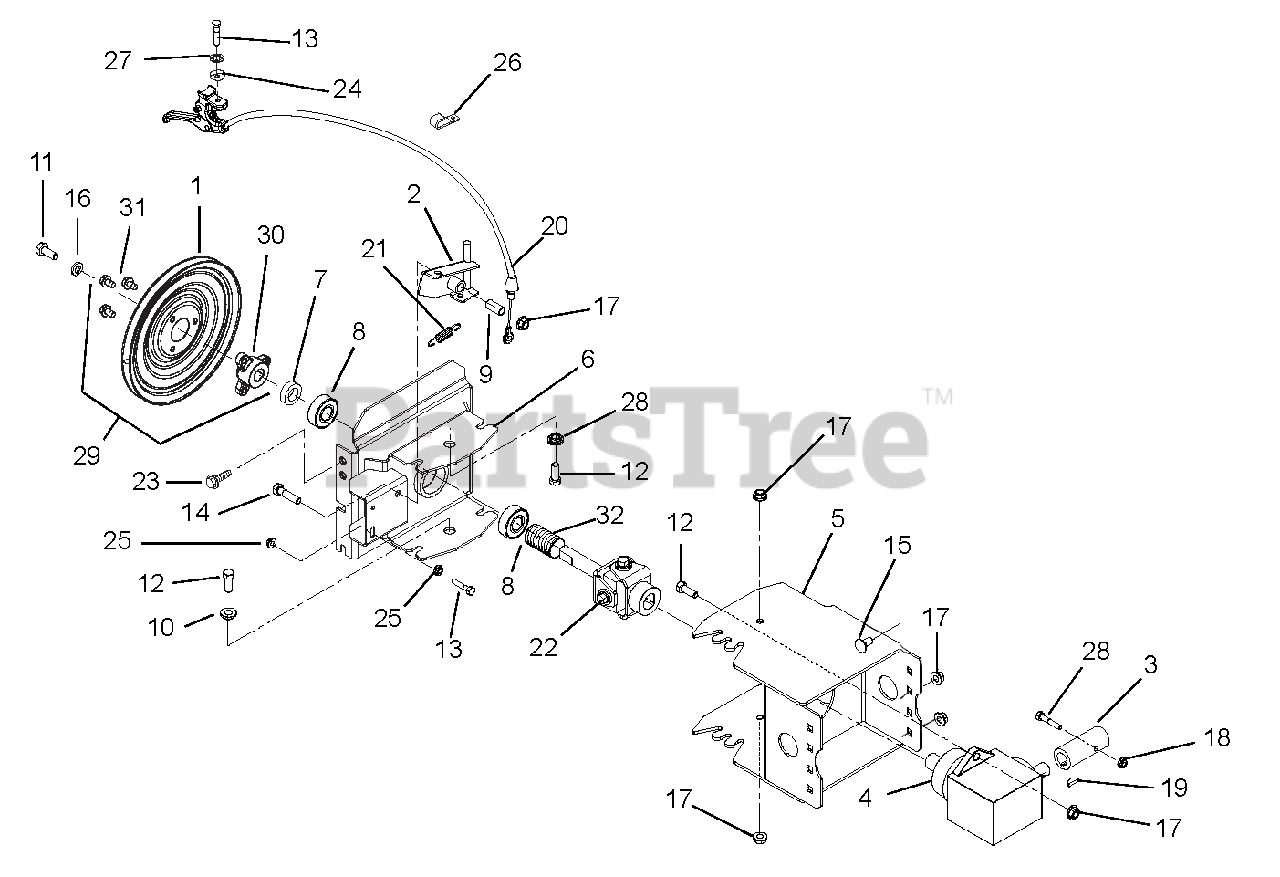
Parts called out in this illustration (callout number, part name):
1	PULLEY,SPIN FORM SINGLE GROOVE
2	ARM, PIVOT LOCK
3	HUB, COUPLING
4	GEAR BOX ASSEMBLY
5	ADAPTER WITH DECAL,BRUSH FRAME
6	ADAPTER, FRAME-20000 SERIES
7	SPACER .755X1.250X.370
8	BRG-BALL .750X1.781X.61
9	BSHG-SLV .385X.500X1.045
10	BSHG-FLG .406X.88X.270X.140
11	BLT-HEX .31-24X.75 YWZC GR5
12	@BLT-HEX .38-16X1.00 GR5 YWZC
13	@BLT-HEX .25-20X1.50 GR5 YWZC
14	@BLT-HEX .38-16X1.75 GR5 YWZC
15	@BLT-RDHDSQNK .38-16X.75 G5YZ
16	WSHR-LK .312X.097 HVY YWZC
17	@NUT-LK-TOP-FLG .38-16 YWZC
18	@NUT-LK-TOP-FLG .25-20 YWZC
19	KEY-WDRF .188X.75X.313 SAE 9
20	CABLE, REMOTE BRUSH LOCK
21	SG-TENS .06X.46X2.00
22	U-JOINT ASSY
23	@SCR-TAP .31-18X.75 HWH TR YWZ
24	SPACER, HANDLEBAR
25	@NUT-SPNLK-FLG .25-20 YWZC
26	J-CLAMP
27	WSHR-LK-INT .250 TH TYA
28	@BLT-HEX .25-20X1.75 GR5 YWZC
29	PULLEY WITH HUB
30	PULLEY HUB, BOLT-ON D-BORE .75
31	@SCR-TAP .31-18X.50 HWH TR YWZ
32	HOSE 4" X 7" FLEX TUBE PV
